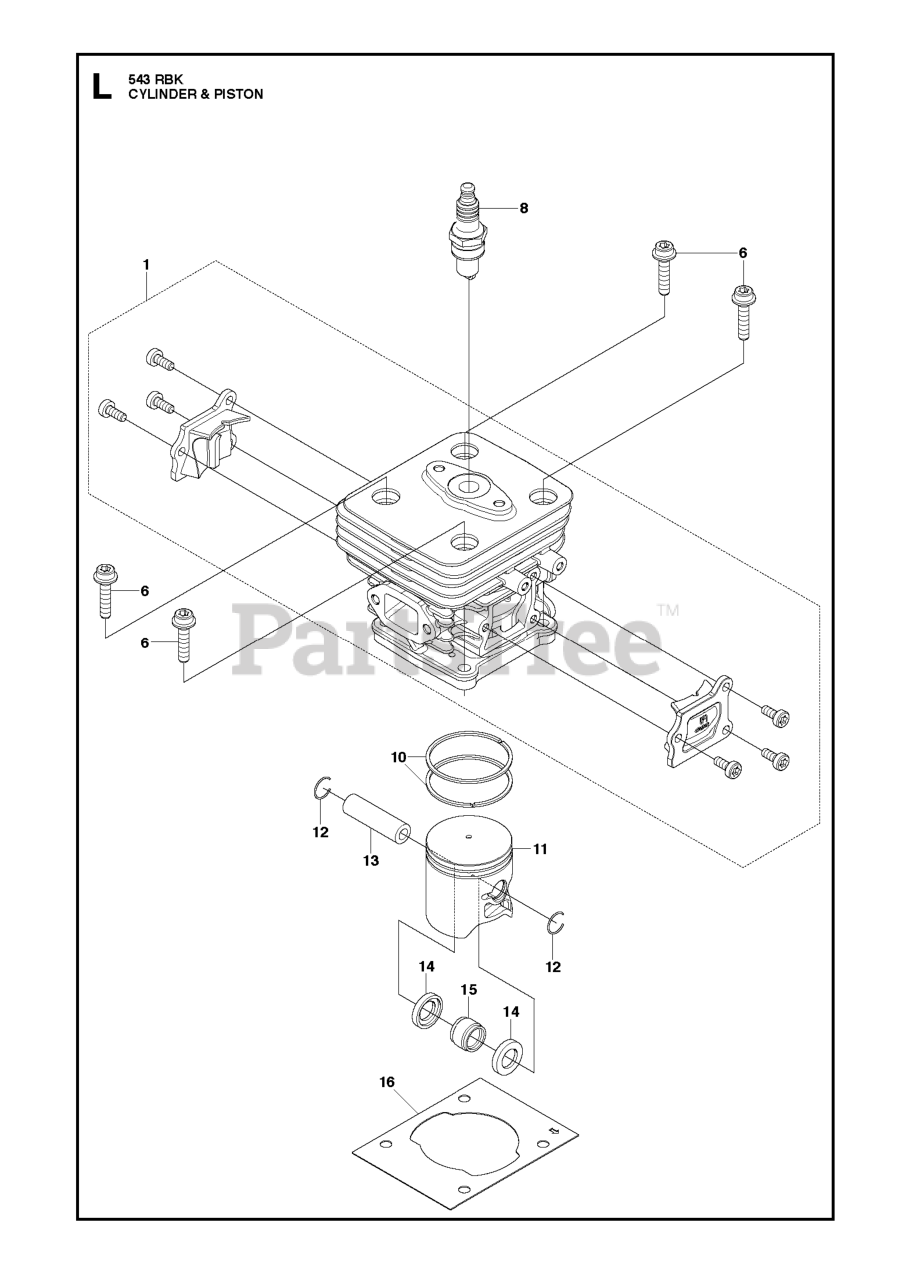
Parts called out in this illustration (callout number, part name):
1	CYLINDER COMP
8	SPARK PLUG CMR7H-10
10	RING PISTON
15	ROLLER BEARING
